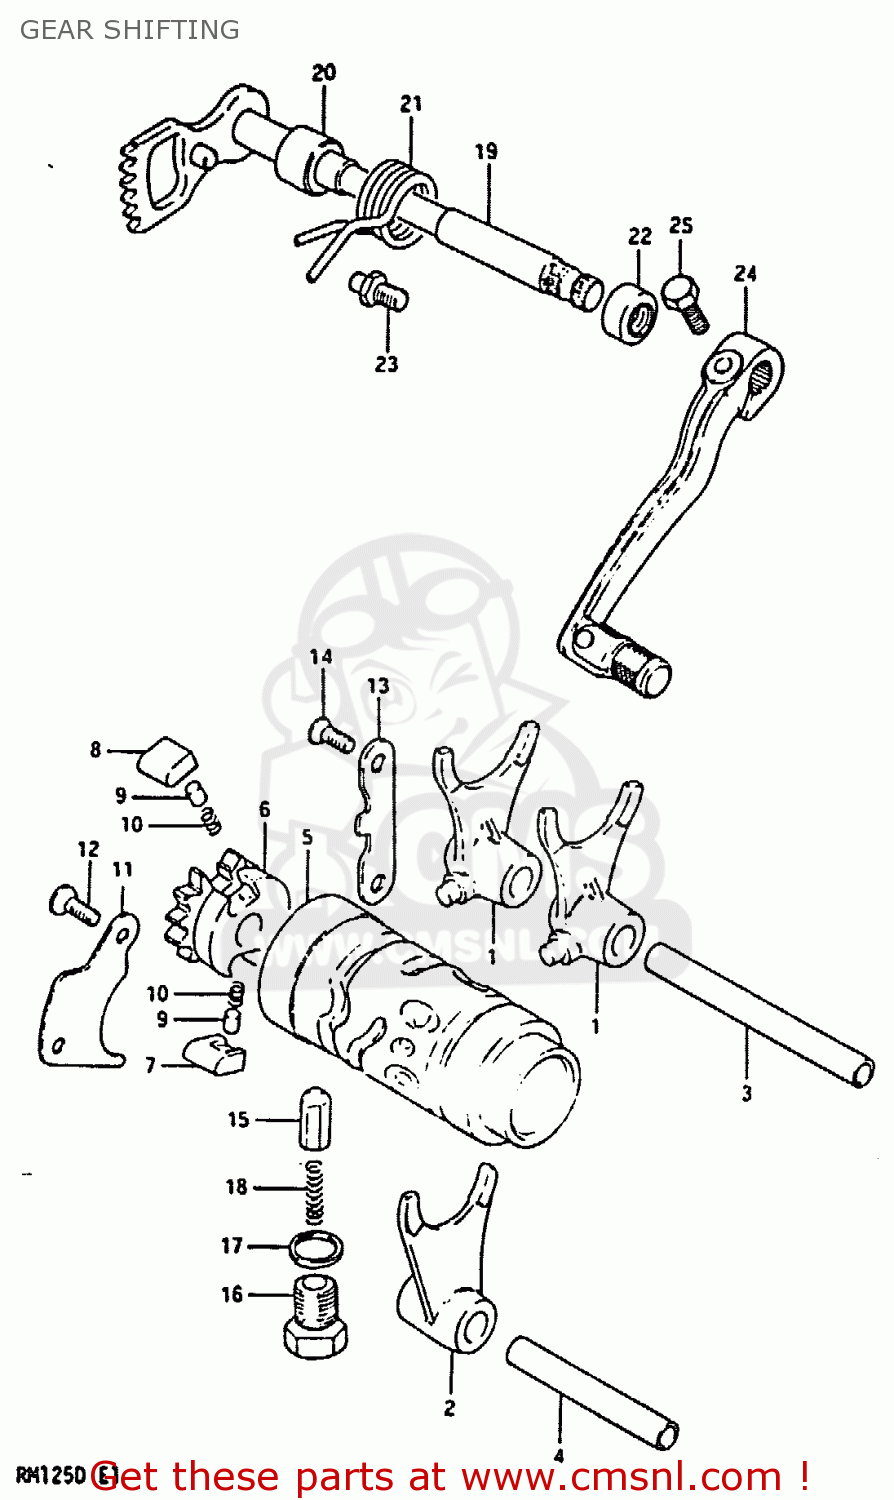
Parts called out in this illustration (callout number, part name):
1	FORK,GEAR SHIFT NO.1
2	FORK,GEAR SHIFT NO.2
3	SHAFT,GEAR SHIFT FORK
4	SHAFT,GEAR SHIFT FORK
5	CAM,GEAR SHIFT
6	RETAINER,GEAR SHIFT CAM
7	PAWL,GEAR SHIFT NO.1
8	PAWL,GEAR SHIFT NO.2
9	PIN(5X8)
10	SPRING
11	LIFTER,GEAR SHIFT PAWL
12	SCREW
13	STOPPER,GEAR SHIFT POLE
14	SCREW
15	STOPPER,GEAR SHIFTING
16	HOUSING,GEAR SHIFT CAM STOPPER
17	GASKET(14X19.2X2) (NAS)
18	SPRING
19	SHAFT,GEAR SHIFT
20	SPACER(12X20X15.3)
21	SPRING
22	OIL SEAL
23	STOPPER,GEAR SHIFT CAM
24	LEVER ASSEMBLY,GEAR SHIFTING
25	BOLT
